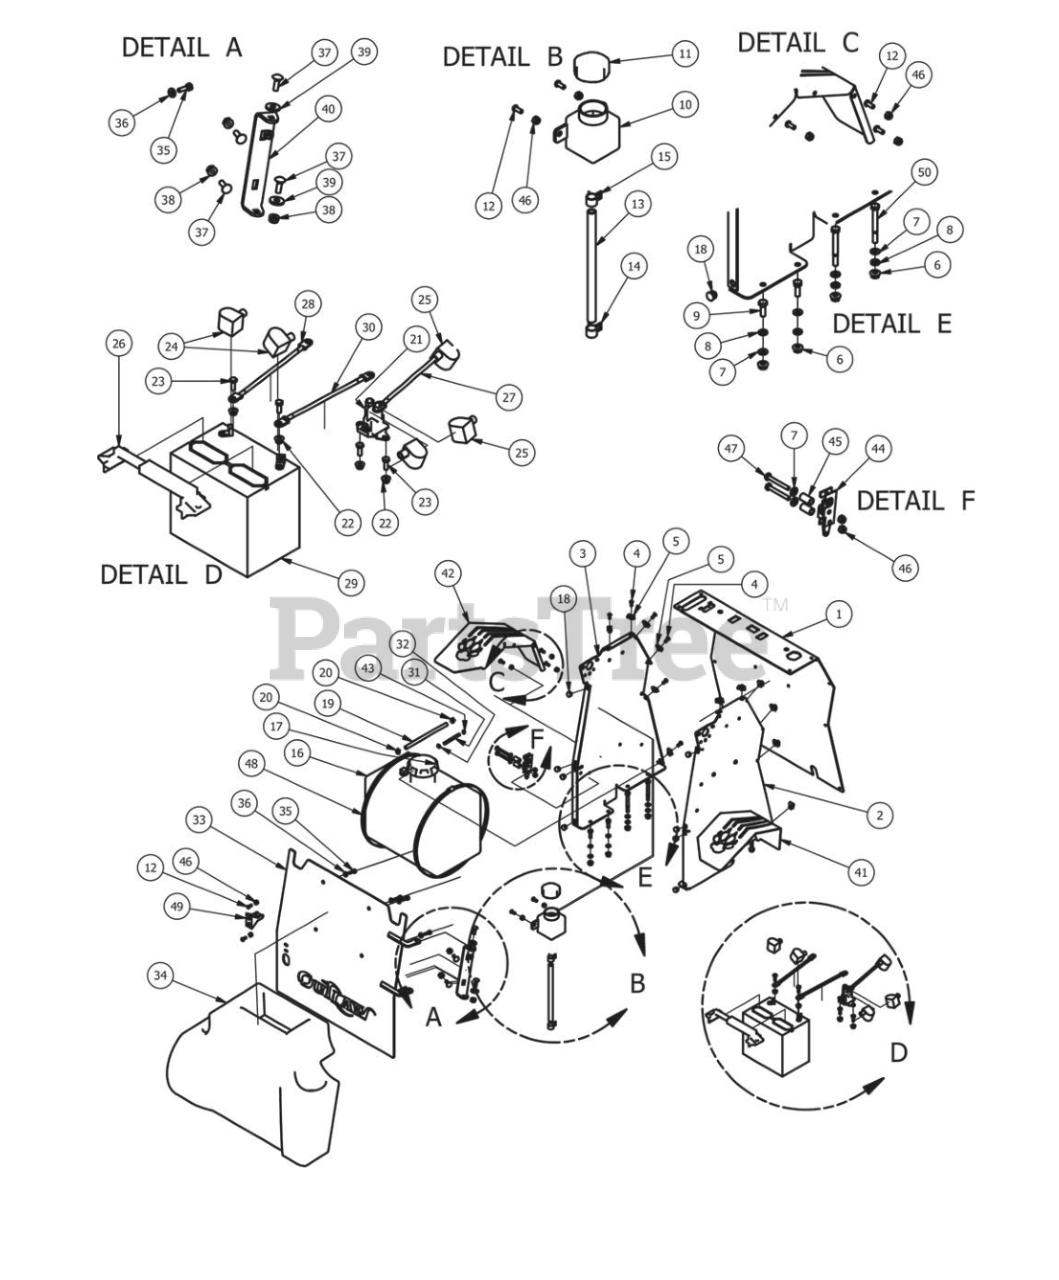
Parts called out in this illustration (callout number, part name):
1	Podium Front Panel
2	Podium Panel Right Side
3	Podium Panel Left Side
4	1/4" x 5/8" BS C/S 18-8 SS
5	1/4-20 Cage Nut
6	5/16" Flange Nut
7	1/4" Flat Washer
8	5/16" Lock Washer
9	5/16" x 1" Bolt
10	350ml Expansion Tank-CZT
11	Hydraulic Tank Cap
12	1/4" x 5/8" BS C/S 18-8 SS
13	3/8 clear hose price per foot
14	1/2 Hose Clamp
15	3/8 hose clamp
16	5 Gal tank w/gauge-Stand On
18	5/8 Round Insert
19	1/4" fuel line hose
20	1/4 fuel clamp
22	1/4-20 Hex Flange Nuts Zinc w/Serrations
23	1/4-20 x 3/4 GR 5 Hex Bolts Zinc
24	Black Boot For ground cable
26	Hold Down Assembly
27	red battery cable alternator to Started cable
28	Ground Cable
29	ZT Battery
30	12 in red battery cable
31	3/16 vinyl tubing
32	3/16 vinyl clamp
33	Door Panel Assembly
34	Cushion-Stand On Mower
35	1/4-20 x 1 GR 5 hex bolt zinc
36	1/4" Flat Washer
37	5/16" x 1" Carriage Bolt
38	5/16-18 Nylon Flange Nut
39	.360 ID Plastic Washer
40	Back Cover Hinge Bracket
41	Fender (Right Side)
42	Fender (Left Side)
43	3/16" Vinyl Hose Clamp
44	Latch-Stand On
45	Brake/Latch Spacer-Stand On
46	1/4" Nylock Nut
47	1/4-20 x 2 Hex Bolt
48	Fuel Tank Clamp-Stand On
49	Latch Striker Post-Stand On
50	5/16" x 3" Hex Bolt
